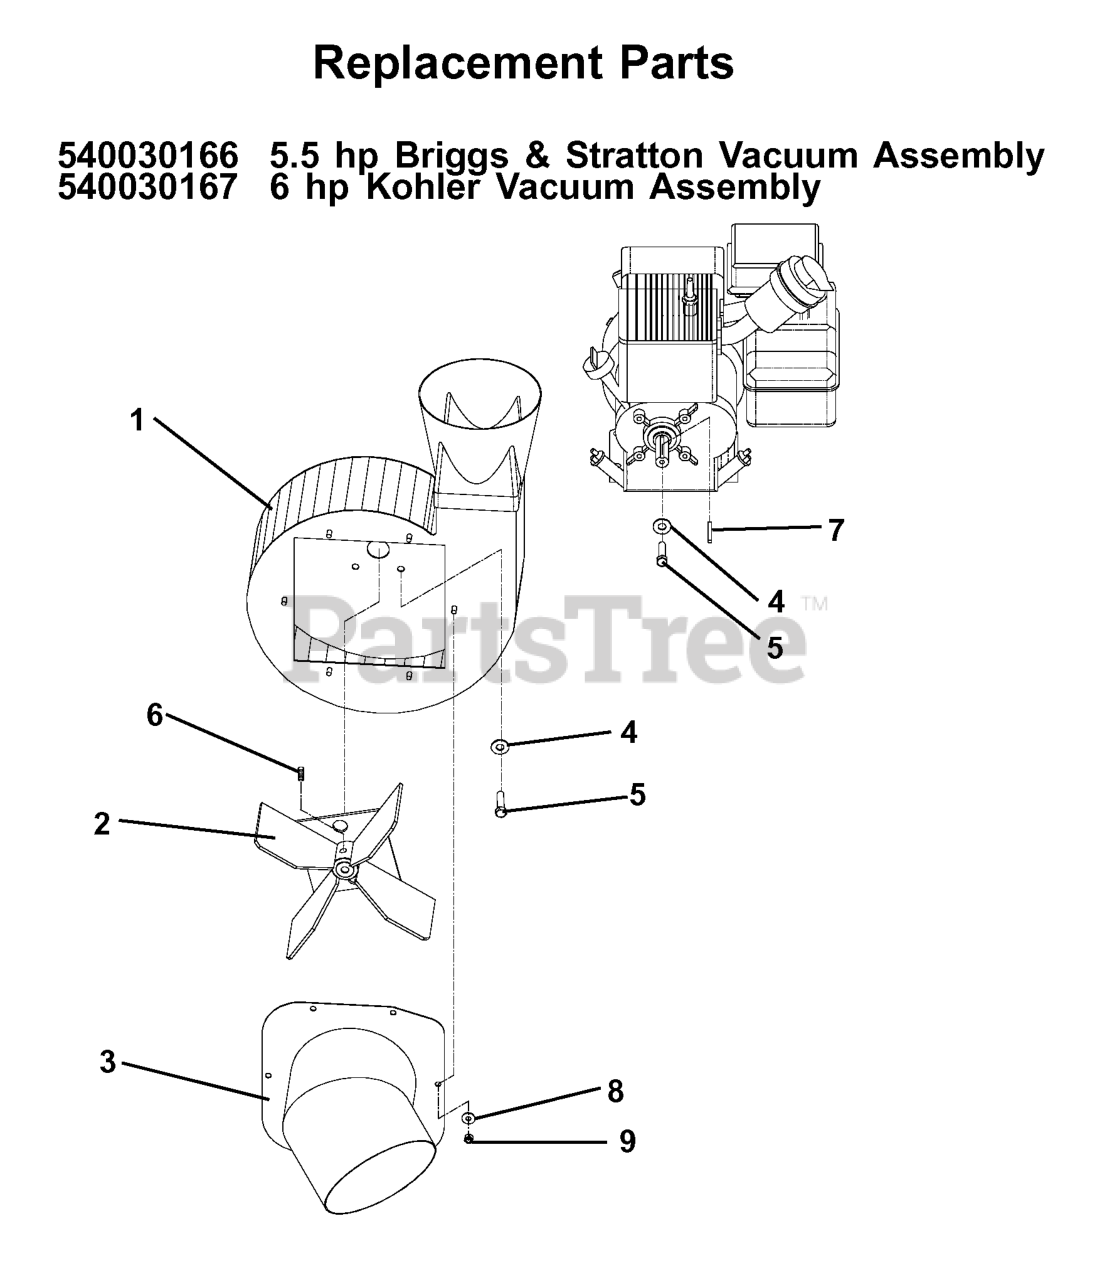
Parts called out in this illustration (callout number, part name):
1	BLOWER HOUSING
2	IMPELLAR
3	BLOWER HOUSING INLET
4	R/B 109600 WASH SPRING, 5/16
5	R/B 990233 BLT HEX 5/16-24X3/4
6	SCREW SET, 3/8-24 X 3/8
7	KEY SQUARE 3/16 X 3/16 X 1 3/4
8	Nut, Hex, Nylon Lock, 1/4"-20
9	Washer, Flat, 1/4"
